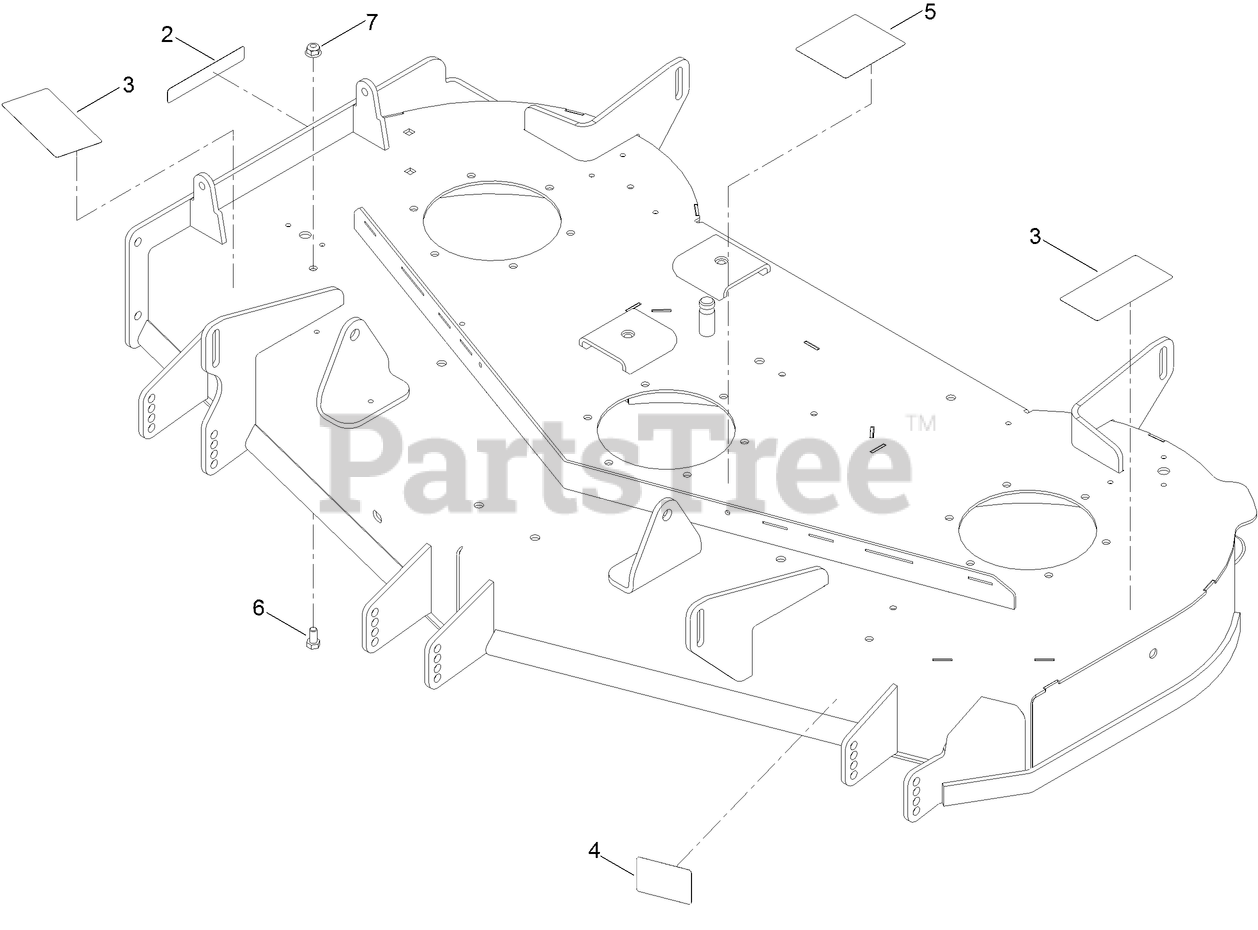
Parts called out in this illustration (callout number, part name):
2	DECAL-DANGER
3	DECAL-DANGER, DECK
4	DECAL-SCALP, ANTI
5	DECAL-ROUTING, BELT
6	SCREW-HH
7	NUT-HF, NI
